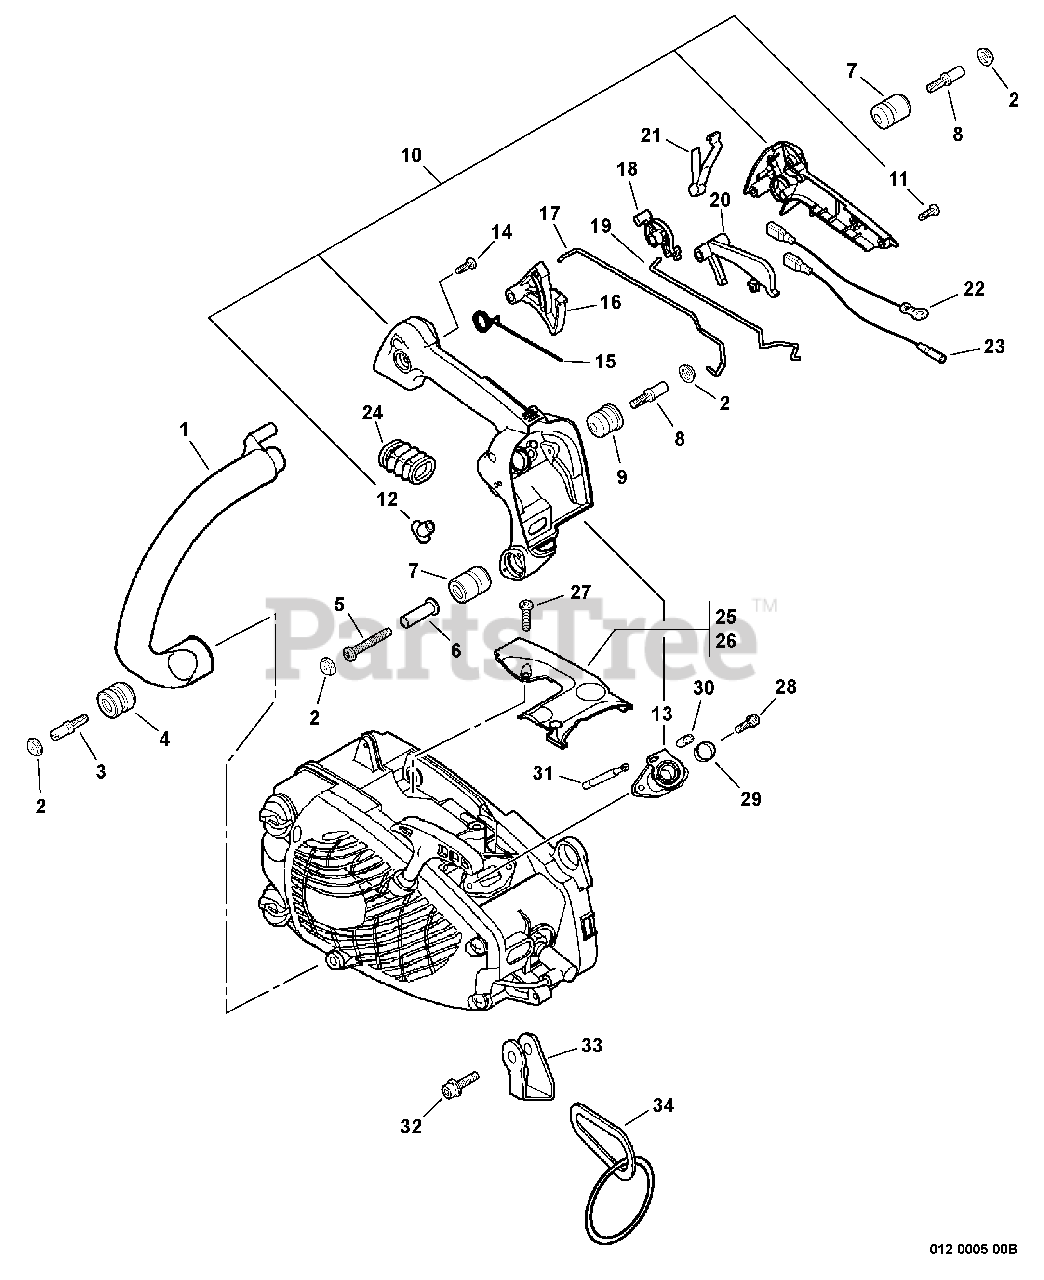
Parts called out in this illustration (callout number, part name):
1	HANDLE - FRONT
2	CAP, CUSHION
5	SCREW - 4X35 -- TAPPING
7	CUSHION
8	STUD, THREADED
9	CUSHION
10	HANDLE SET - REAR
11	SCREW - 4X16
13	BELLOWS, INTAKE
14	SCREW - 5X20 -- TAPPING
15	SPRING, TRIGGER
16	TRIGGER, THROTTLE
17	ROD, THROTTLE
18	LEVER, CHOKE
19	ROD, CHOKE
20	LEVER, TRIGGER LOCKOUT
21	TERMINAL - GROUND
22	LEAD - GROUND
23	LEAD - IGNITION
24	BELLOWS, INTAKE
25	COVER, DUST - GRAY
26	COVER, DUST - ORANGE
27	SCREW - 4X12 -- TAPPING
28	SCREW - 5X12
29	COLLAR - 16
30	ADAPTOR
31	PIPE
32	SCREW - 4X25
33	BRACKET, STRAP
34	HANGER KIT
